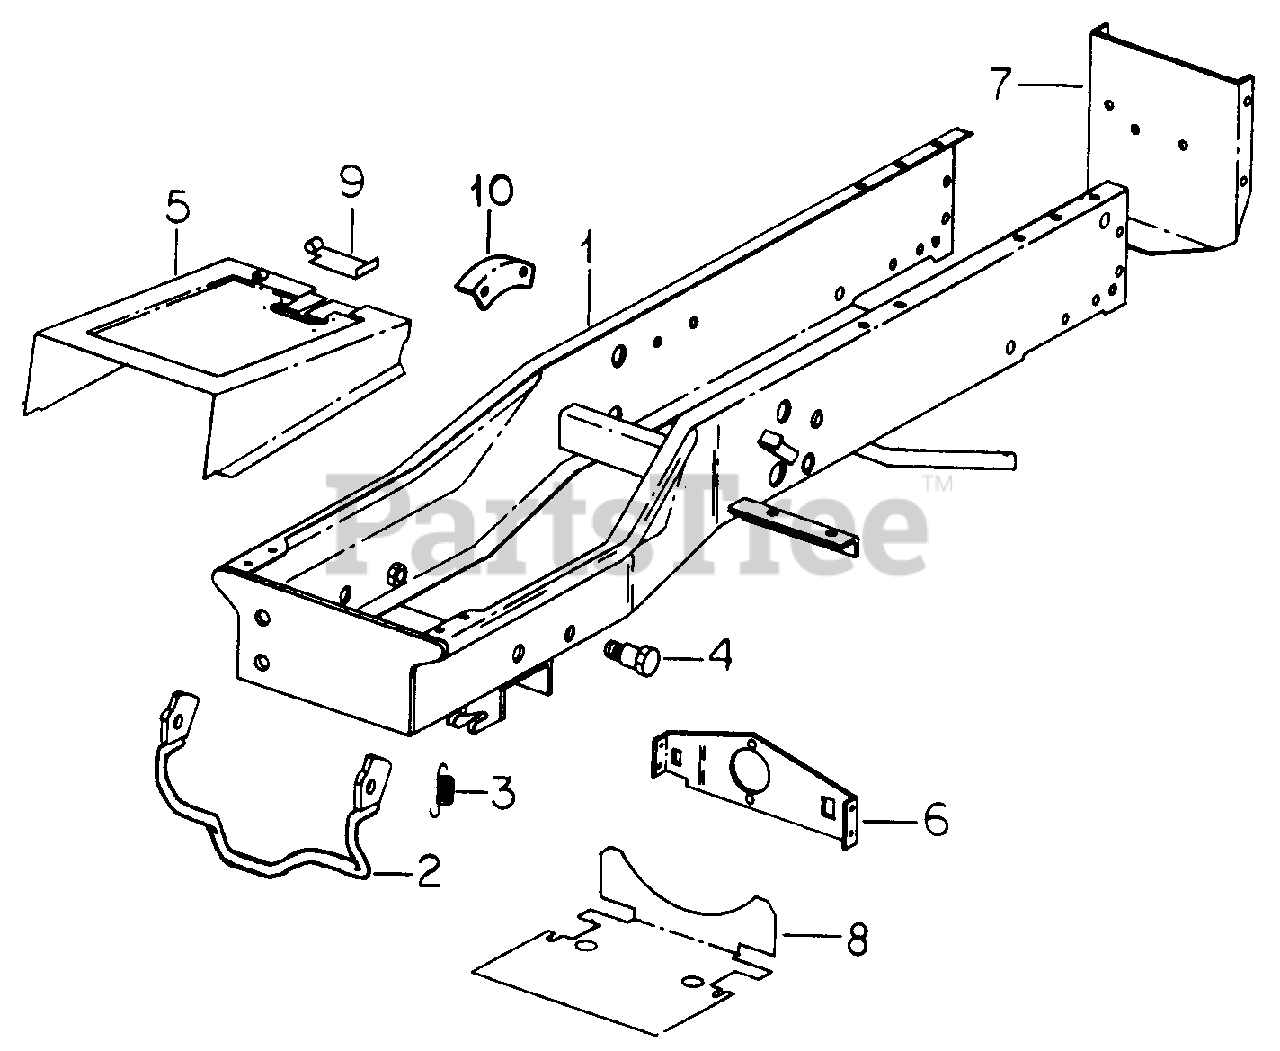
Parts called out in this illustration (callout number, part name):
3	Spring, Latch
4	Bolt, Implement Mtg Shoulder
5	Cover Assy, Frame w/Product Graphic
6	Bracket, Angle Drive
8	Cover, Lower Frame
9	Stop, 2nd Gear
10	Bracket, Indicator
